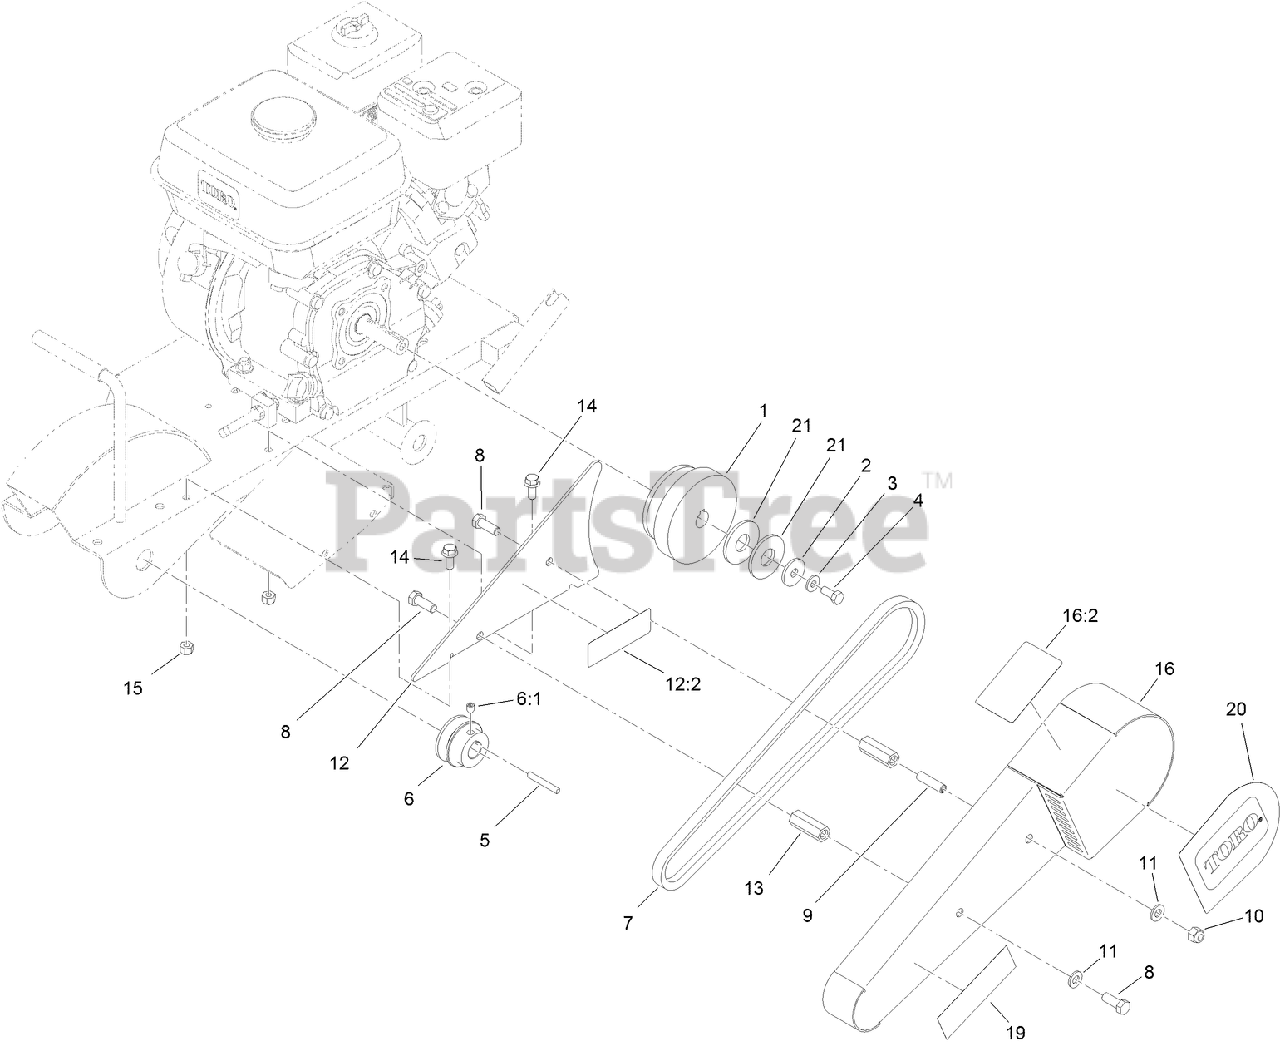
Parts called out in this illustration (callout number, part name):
1	CLUTCH-CENTRIFUGAL
2	WASHER
3	WASHER-FLAT
4	SCREW-HH
5	KEY-SQUARE
6	PULLEY-FRONT
6:1	SCREW-HSH
7	BELT-DRIVE
8	SCREW-HH
9	SCREW-SET, HSH
10	NUT-LOCK, NI
11	WASHER-FLAT
12	PLATE-GUARD, INNER
12:2	DECAL-WARNING, SHIELDS
13	SPACER-GUARD, BELT
14	SCREW-HHF
15	NUT-LOCK, NI
16	BELT GUARD ASM
16:2	DECAL-CAUTION
21	WASHER-FLAT
